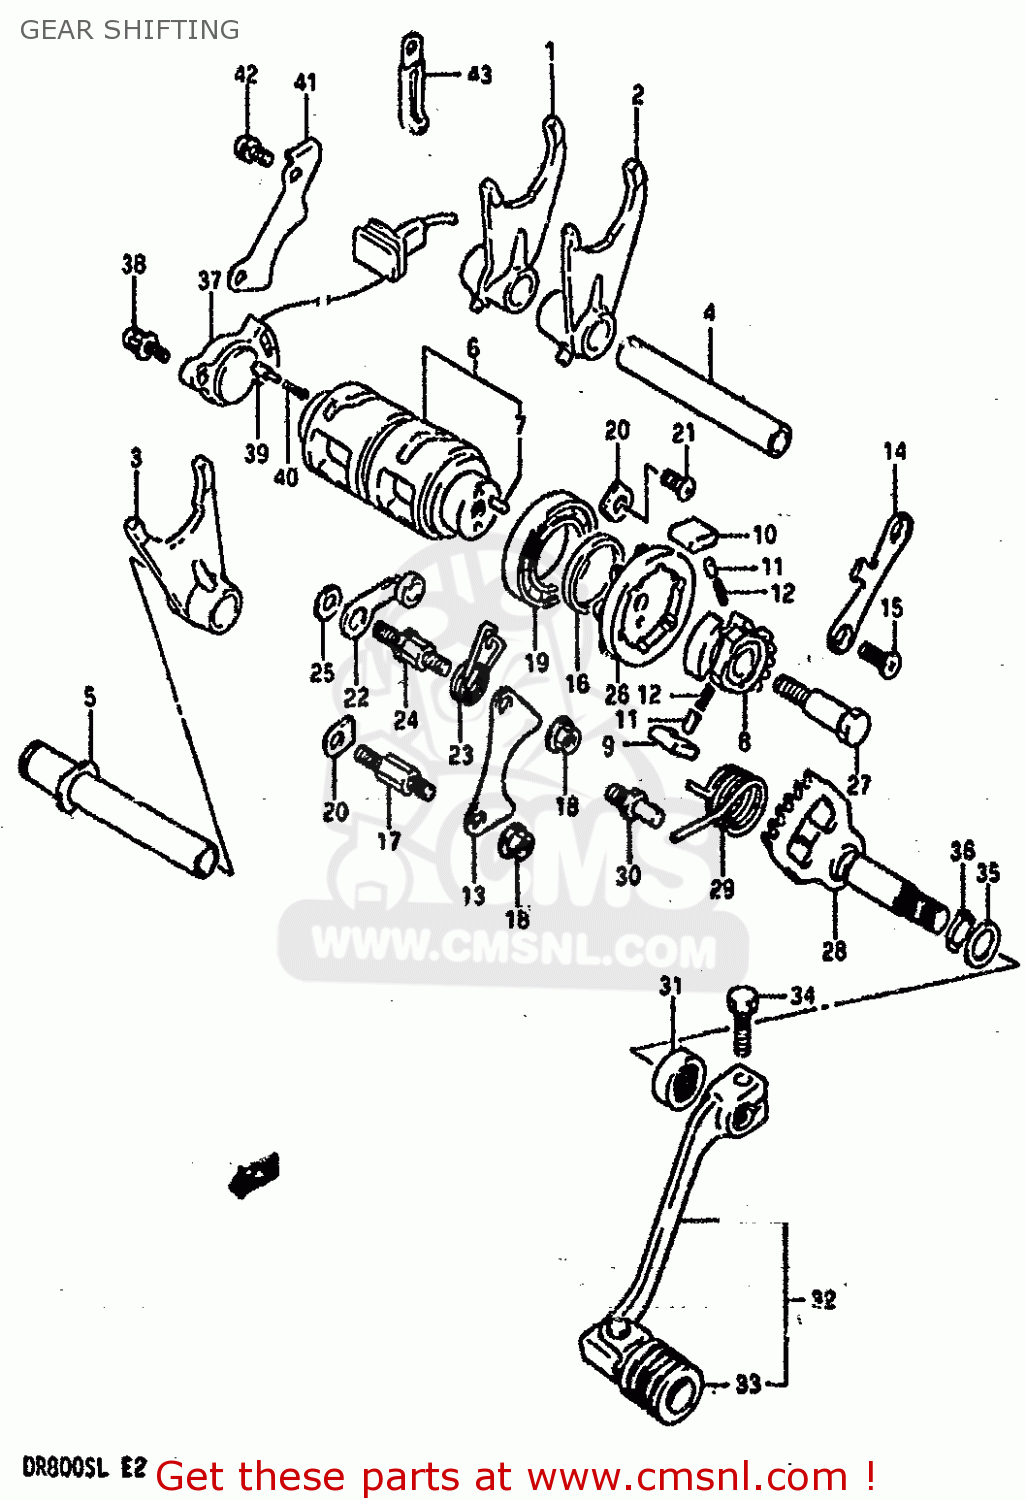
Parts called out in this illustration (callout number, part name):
1	FORK,GEAR SHIFT NO.1
2	FORK,GEAR SHIFT NO.2
3	FORK, GEAR SHIFTING NO.3
4	SHAFT,GEAR SHIFT FORK NO.1
5	SHAFT,FORK NO.2
6	CAM,GEAR SHIFT
7	PIN
8	GEAR,GEARSHIFT CAM DRIVE
9	PAWL,GEAR SHIFT NO.1
10	PAWL,GEAR SHIFT NO.2
11	PIN(5X8)
12	SPRING
13	LIFTER,GEAR SHIFT POLE
14	GUIDE,GEAR SHIFT CAM
15	SCREW
16	WASHER(25X32X3)
17	BOSS,SHIFT PAWL LIFTER
18	NUT
19	BEARING
20	RETAINER,SHIFT CAM,R BEARING
21	SCREW 6X12
22	STOPPER,GEAR SHIFT CAM
23	SPRING
24	SPRING,STOPPER ARM
25	WASHER
26	PLATE,GEAR SHIFT CAM
27	PIN,SHIFT CAM DRIVEN GEAR
28	SHAFT,GEAR SHIFT
29	SPRING
30	STOPPER,GEAR SHIFT ARM
31	OIL SEAL
32	LEVER,GEARSHIF
33	RUBBER,GEAR SHIFT PEDAL
34	BOLT
35	WASHER
36	CIRCLIP
37	BASE ASSY,NEUTRAL SW TERMINAL
38	SCREW
39	PIN(5X15.5)
40	SPRING
41	CLAMP, LEAD WIRE
42	SCREW
43	CLAMP L:35
